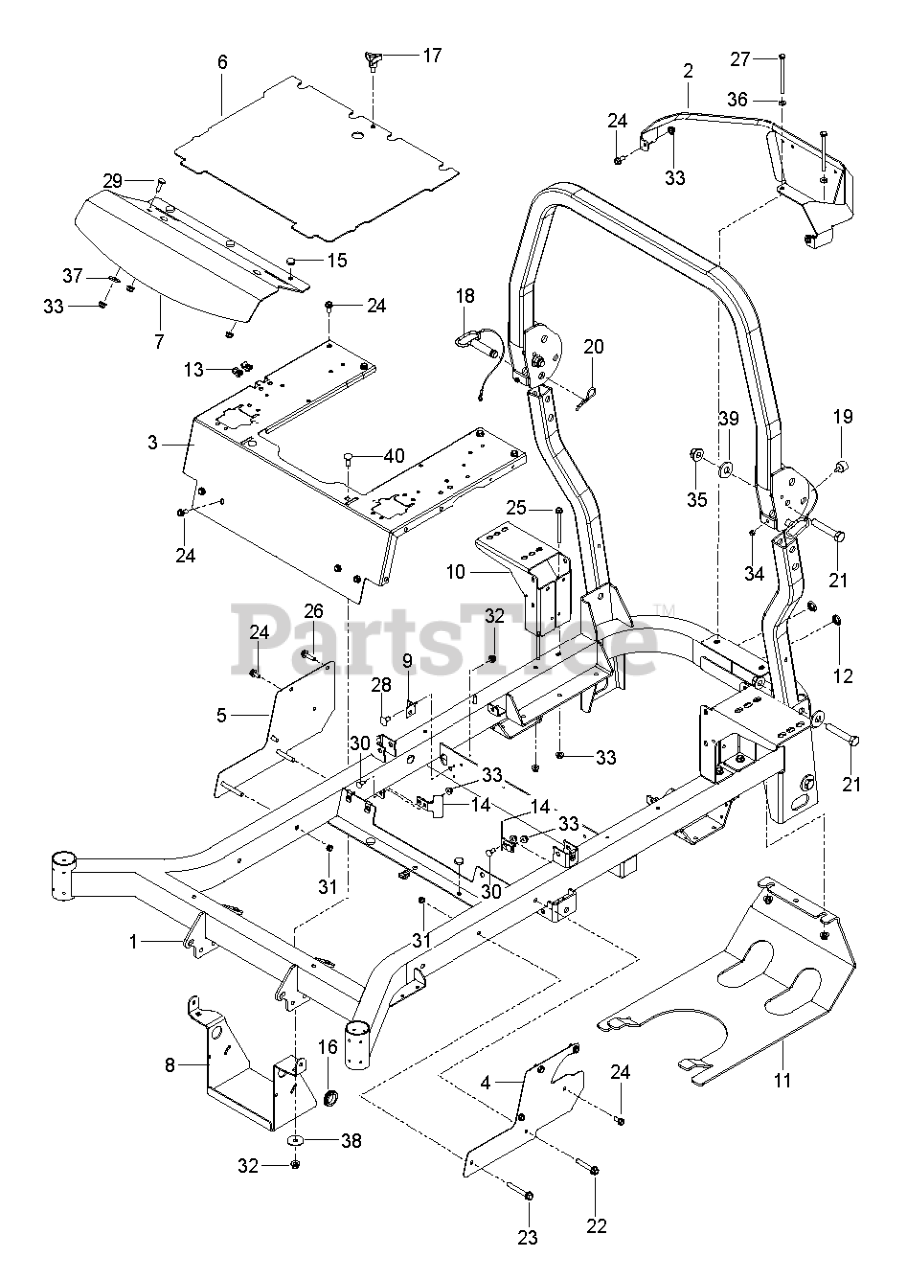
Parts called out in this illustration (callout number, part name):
1	KIT.FRAME.W/DECALS.X668
2	GUARD.PNT.REAR.MZ.GRAY
3	SUPPORT.PNT.SEAT.CONTROL.ORNG
4	BRACKET SIDE, LT ORANGE
5	BRACKET SIDE, RT ORANGE
6	PLATE, FLOOR W/DECALS
7	PLATE, FOOTREST
8	BRACKET BATTERY BLACK MS-431
9	BRACKET.DAMPENER.BLACK
10	MOUNT, TANK, ZT BLK
11	Husqvarna TBD
12	CAP.PLUG.BP-1.BLACK
13	U-CLIP 5/16-18 NUT RETAINER
15	GROMMET, BUMPER
16	RUBBER GROMMET
17	KNOB W/STUD
18	HHFS 3/8-16 X 2.5 GR 5 ZD
19	HHFS 3/8-16 X 2-3/4 GR5 ZD
20	HHFS 5/16-18 X 3/4
21	BOLT.HEX.FLNG.5/16-18X3.75
22	HHFS 5/16-18 X 1.25 TPBLT GD 5
23	HCS 5/16C X 4
24	RHSNB 3/8-16 X 3/4 GR 5 BLK ZN
27	NUT HEX 3/8-16 NYLON, THIN
28	NUT 3/8-16 HEX FLG NYLOC ZD
29	5/16-18 NYLOC FLANGE NUT
30	WASHER
31	WASHER 1/2" FLAT
32	NUT 3/8-16 HEX FLG NYLOC ZD
33	5/16-18 NYLOC FLANGE NUT
34	LOCKNUT.NYLOC.1/4-20
35	NUT 5/8-11 FLG NYLOC ZD
36	WASHER
37	WASHER 1/2" FLAT
38	WASHER.13/32X1-1/2X16GA
39	WASHER, 5/8 FLAT
40	RHSNB 3/8C X 1
